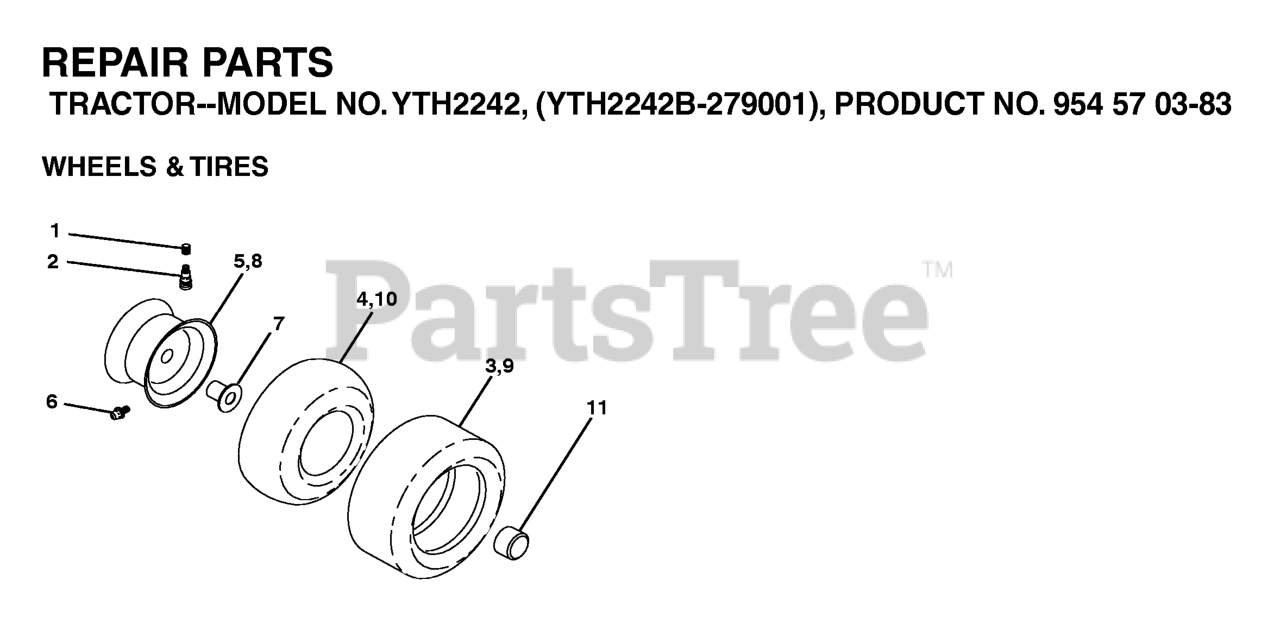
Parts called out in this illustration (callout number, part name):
2	VALVE STEM LT
3	TIRE HEAVY DUTY
4	TUBE.5.3/4.5/6
5	RIM ASM 6" FRONT SILVER
6	FITTING LT
7	BEARING T
8	RIM ASM 8" REAR SILVER
9	TIRE.TS.20X10-8
10	TUBE
11	CAP, AXLE BLK
